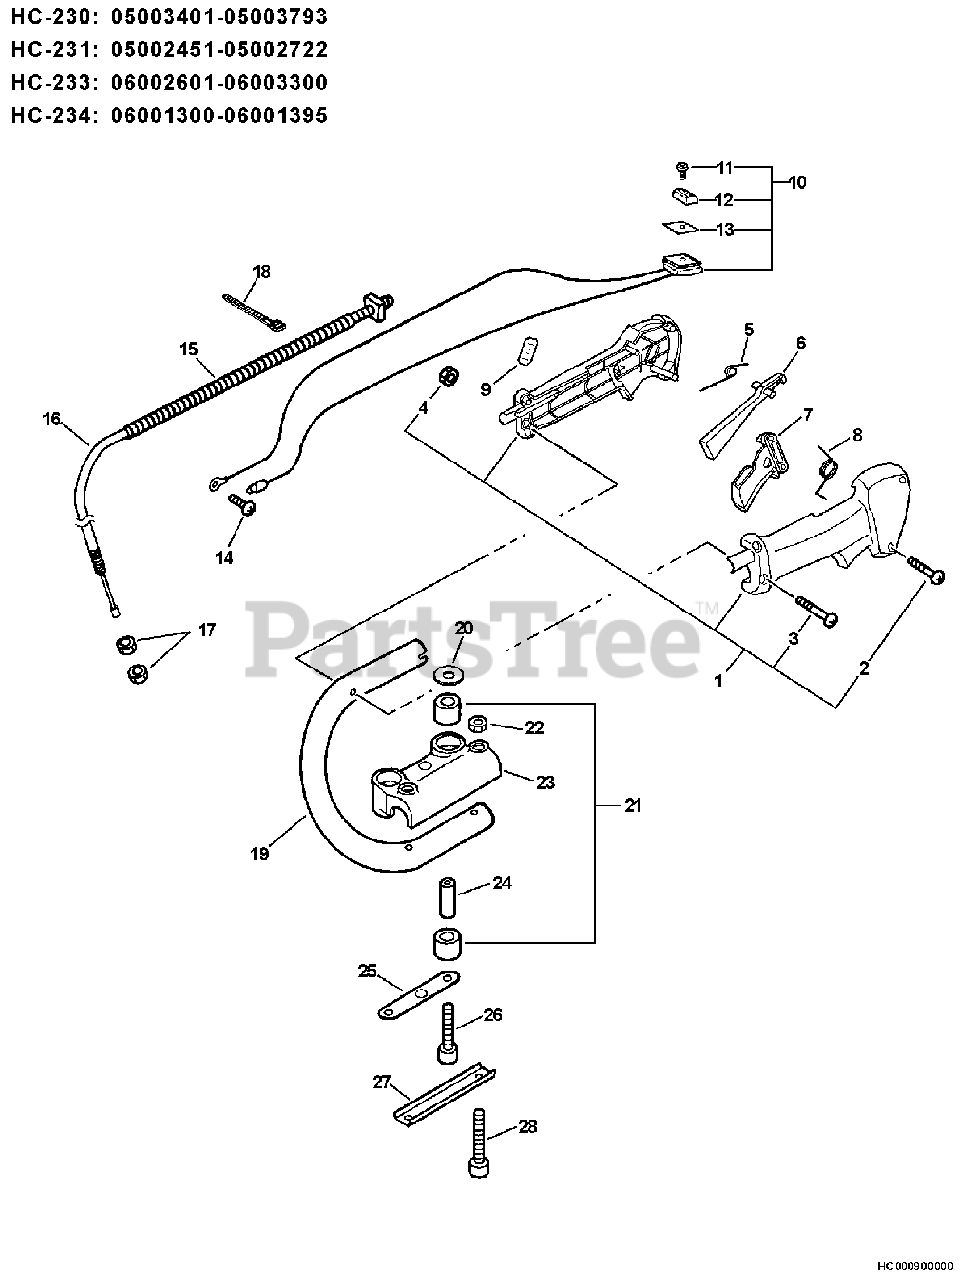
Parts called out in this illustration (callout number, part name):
1	CONTROL HANDLE ASSY
2	SCREW - 4X16
3	SCREW - 5X30
5	SPRING, LOCKOUT LEVER
6	LEVER, TRIGGER LOCKOUT
7	TRIGGER, THROTTLE
8	SPRING, TRIGGER
10	IGNITION SWITCH ASSY
11	SCREW - 3X10
12	KNOB, SWITCH - ORANGE
13	COVER, SWITCH - STOP
14	SCREW - 5X10
15	TUBE, PROTECTIVE - CORRUGATED
16	CABLE, THROTTLE
18	TIE, CABLE - SMALL
19	HANDLE - REAR
23	BRACKET, HANDLE - UPPER
24	SPACER
26	SCREW - 5X40
27	BRACKET, HANDLE - LOWER
28	SCREW - 5X35
